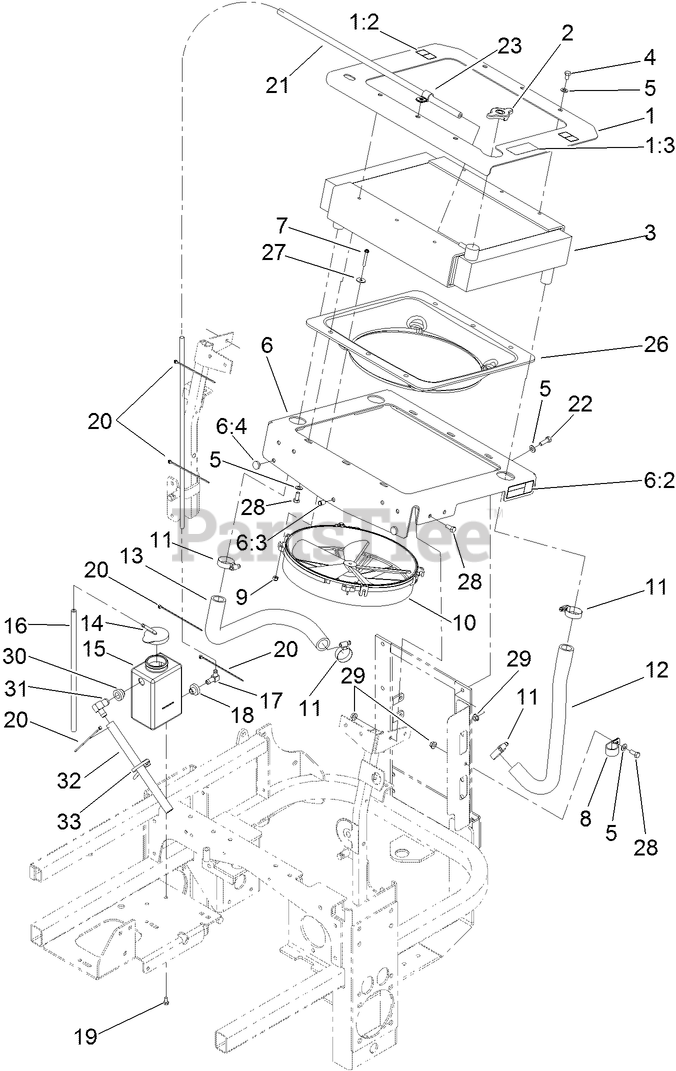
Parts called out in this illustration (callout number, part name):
1	TOP RADIATOR PLATE ASM
1:2	DECAL-SURFACE, HOT
1:3	DECAL-ANTIFREEZE
2	CAP-RADIATOR
3	RADIATOR
4	SCREW-HH
5	WASHER-PLAIN
6	BOTTOM RADIATOR PLATE ASM
6:2	DECAL-DANGER
6:3	NUT-CLINCH
6:4	BUMPER
7	SCREW-HWH
8	CLIP-LOOM
9	NUT-LOCK, HH
12	HOSE-RADIATOR, LH
13	HOSE-OUTLET, ENGINE
14	CAP-TANK, OVERFLOW
15	TANK-OVERFLOW
16	HOSE-LINE, FUEL
19	SCREW-HH
20	TIE-CABLE
21	HOSE-OVERFLOW
22	SCREW-HH
23	CLIP-LOOM
26	SHROUD-COOLING, ENGINE
27	WASHER
28	SCREW-HH
29	NUT-HF
31	FITTING-ELBOW
32	HOSE-OVERFLOW
33	TIE-PLASTIC
